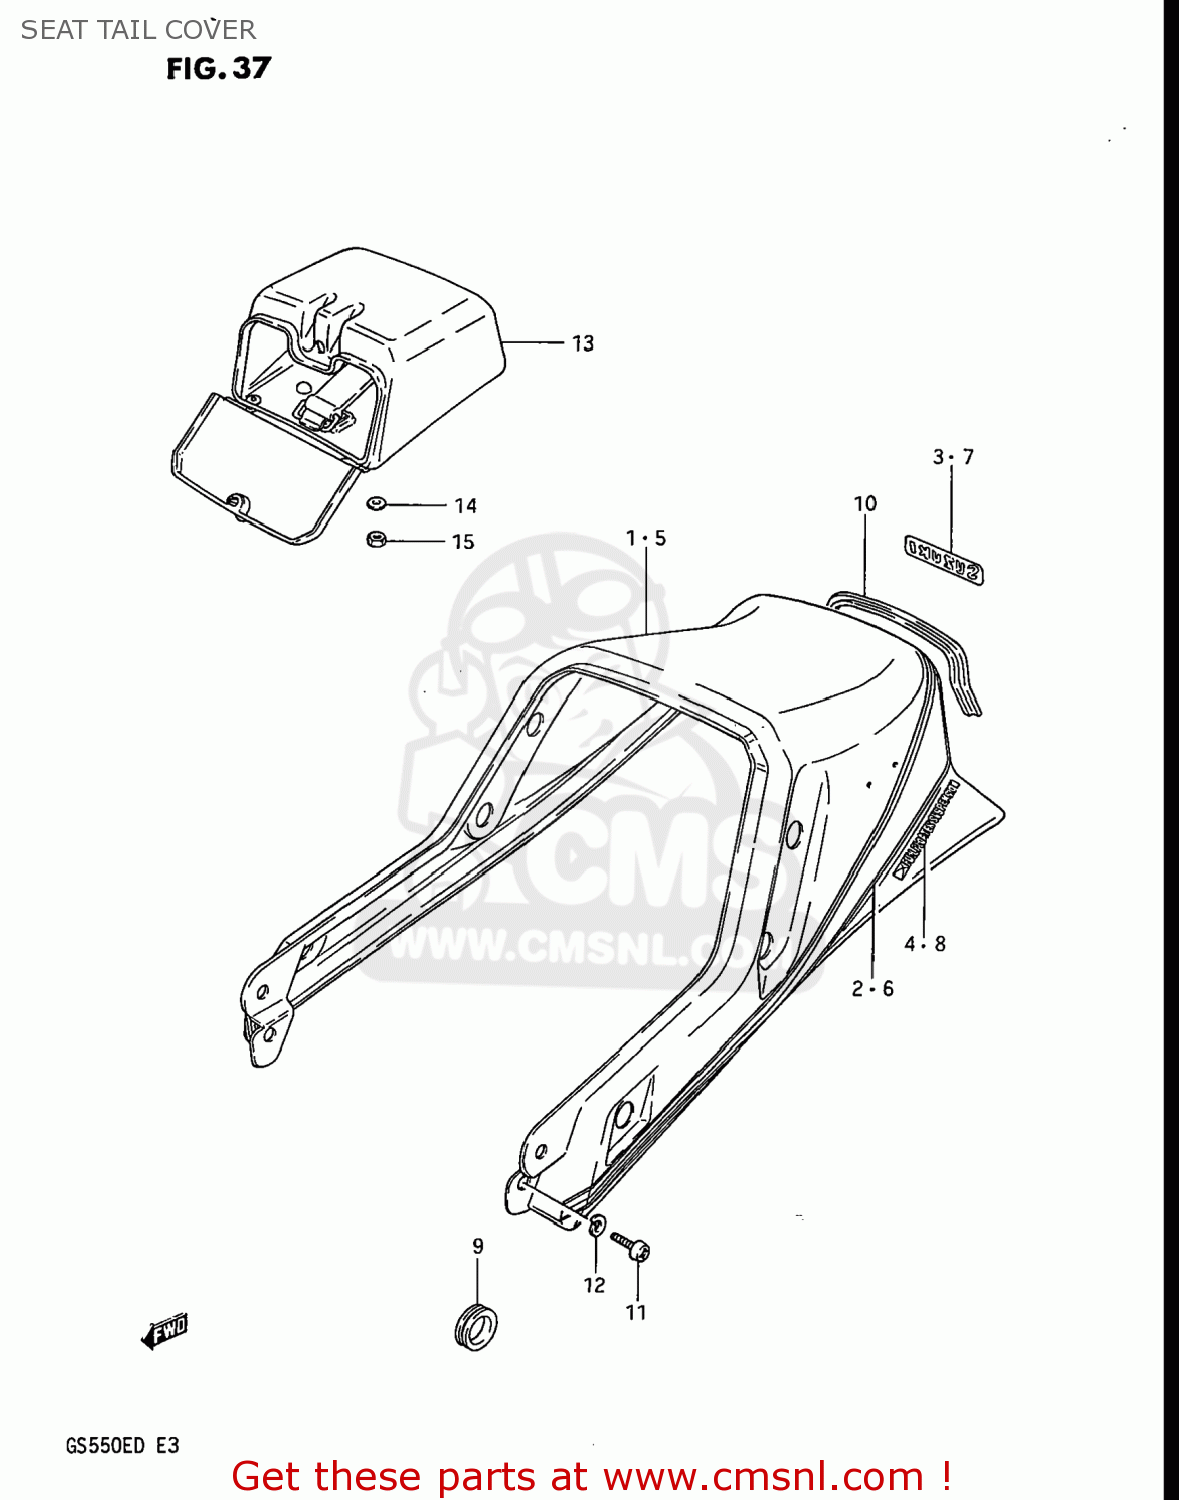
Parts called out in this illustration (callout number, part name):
1	COVER COMP,SEAT TAIL
2	TAPE SET,SEAT TAIL COVER
3	EMBLEM(WHITE)
4	EMBLEM
5	COVER COMP,SEAT TAIL
6	TAPE SET,SEAT TAIL COVER
7	EMBLEM(WHITE)
8	EMBLEM
9	GROMMET,SEAT LOCK HOLE
10	BLIND,SEAT TAIL COVER
11	SCREW
12	LOCK WASHER
13	BOX,SEAT TAIL
14	WASHER
15	NUT
